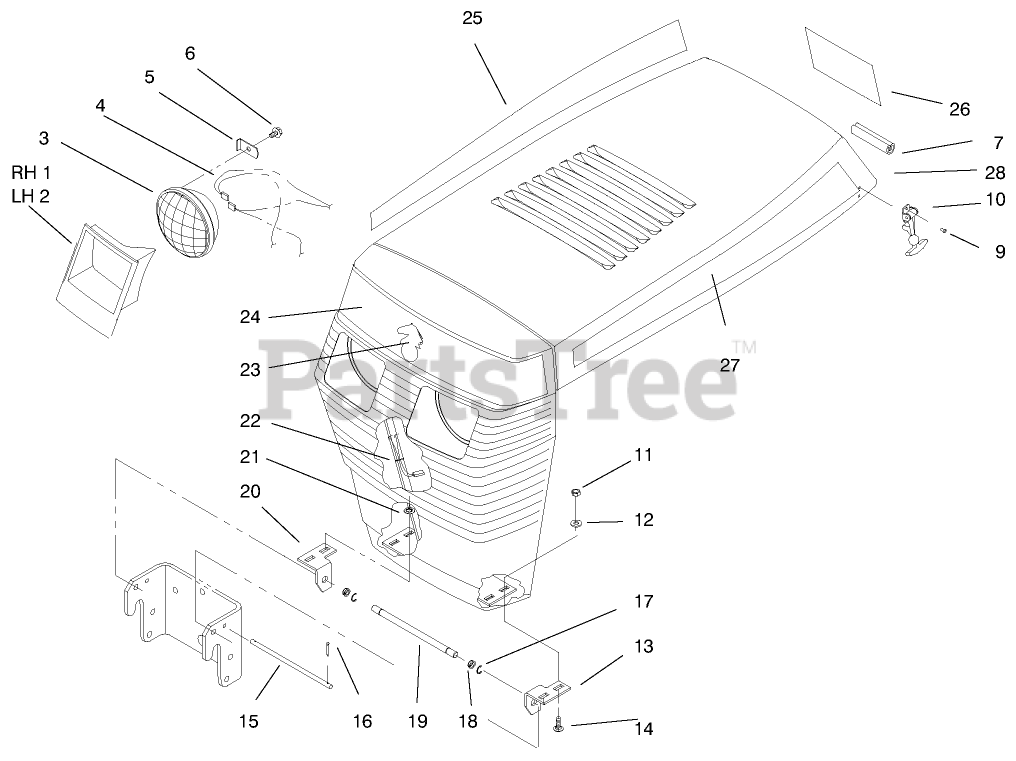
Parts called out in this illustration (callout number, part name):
3	HEADLAMP
5	LOCK-HEADLIGHT
6	SCREW-HWH
7	EDGING-CONSOLE
8	SCREW-HH
9	RIVET-POP
10	HANDLE ASM
11	NUT-LOCK, NI
12	WASHER-FLAT
13	BRACKET-GRILL, LH
15	ROD-HOOD STOP
17	BUSHING-NYLINER
18	RING-RETAINING
19	ROD-GRILL PIVOT
20	BRACKET-GRILL, R H
21	WASHER-LOCK, INTERNAL
22	TIE-CABLE
24	DECAL-FRONT HOOD, TOP
